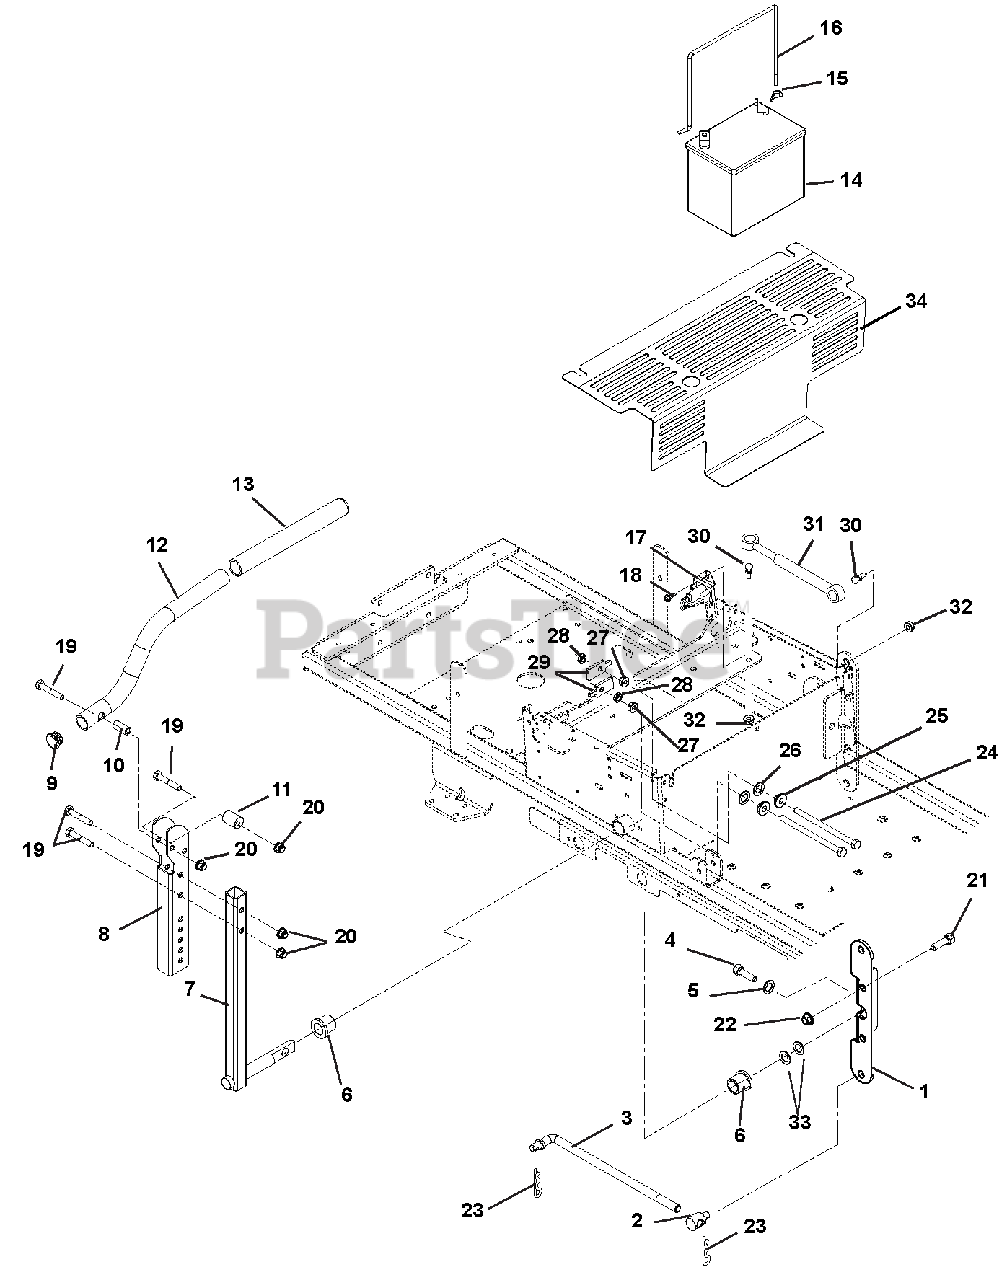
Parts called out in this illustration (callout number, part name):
1	LINK, CONTROL
2	PIVOT, ROD (TRUNNION ) .50
3	LINK,WIREFORM
4	BLT-HEX .38-16X1.0 GR8 YZ EP30
5	WSHR-FL-STL .390X1.5X.125 YWZC
6	BUSHING-1"X.75"X1"
7	WELDMENT, CONTROL ARM
8	CHANNEL, UPPER HANDLEBAR
9	CAPLUG, HANDLEBAR
10	BSHG, SPCR .330X.500X1.01 PM
11	BSHG,ECCEN .328X.750X1.01 PM
12	HANDLE BAR
13	GRIP - HANDLEBAR
14	Battery, Exide Sealed Maintenance Free U1-250 (Purchase replacement locally)
15	NUT-LK WING .250-20 YWZC
16	BATTERY ROD
17	SOLENOID, HP RTV
18	@SCR-TAP .25-20X.37 HWH YWZ TR
19	@BLT-HEX .31-18X1.75 GR5 YWZC
20	@NUT-LK-NYL-FLG .31-18 YWZC
21	@BLT-HEX .38-16X1.25 GR5 YWZC
22	NUT-HEX-JAM .375-16 YWZC
23	PIN-HAIR INT .08X.18X1.18 YWZC
24	BLT-HEX,5/16-18X5 G2 HH YWZC
25	BSHG-FLG .32X.500X.344X.880
26	WSHR-FL-STL .52X.827X.062 YWZC
27	@NUT-SPNLK-FLG .312-18 YWZC
28	NUT- JAM .312-18 YWZC
29	STOP TAB
30	STUD- BALL
31	DAMPER, CONTROL
32	@NUT-LK-TOP-FLG .31-18 YWZC
33	WSHR-FL-STL .755X1.25X.125 YZ
34	BRKT, FAN GUARD
